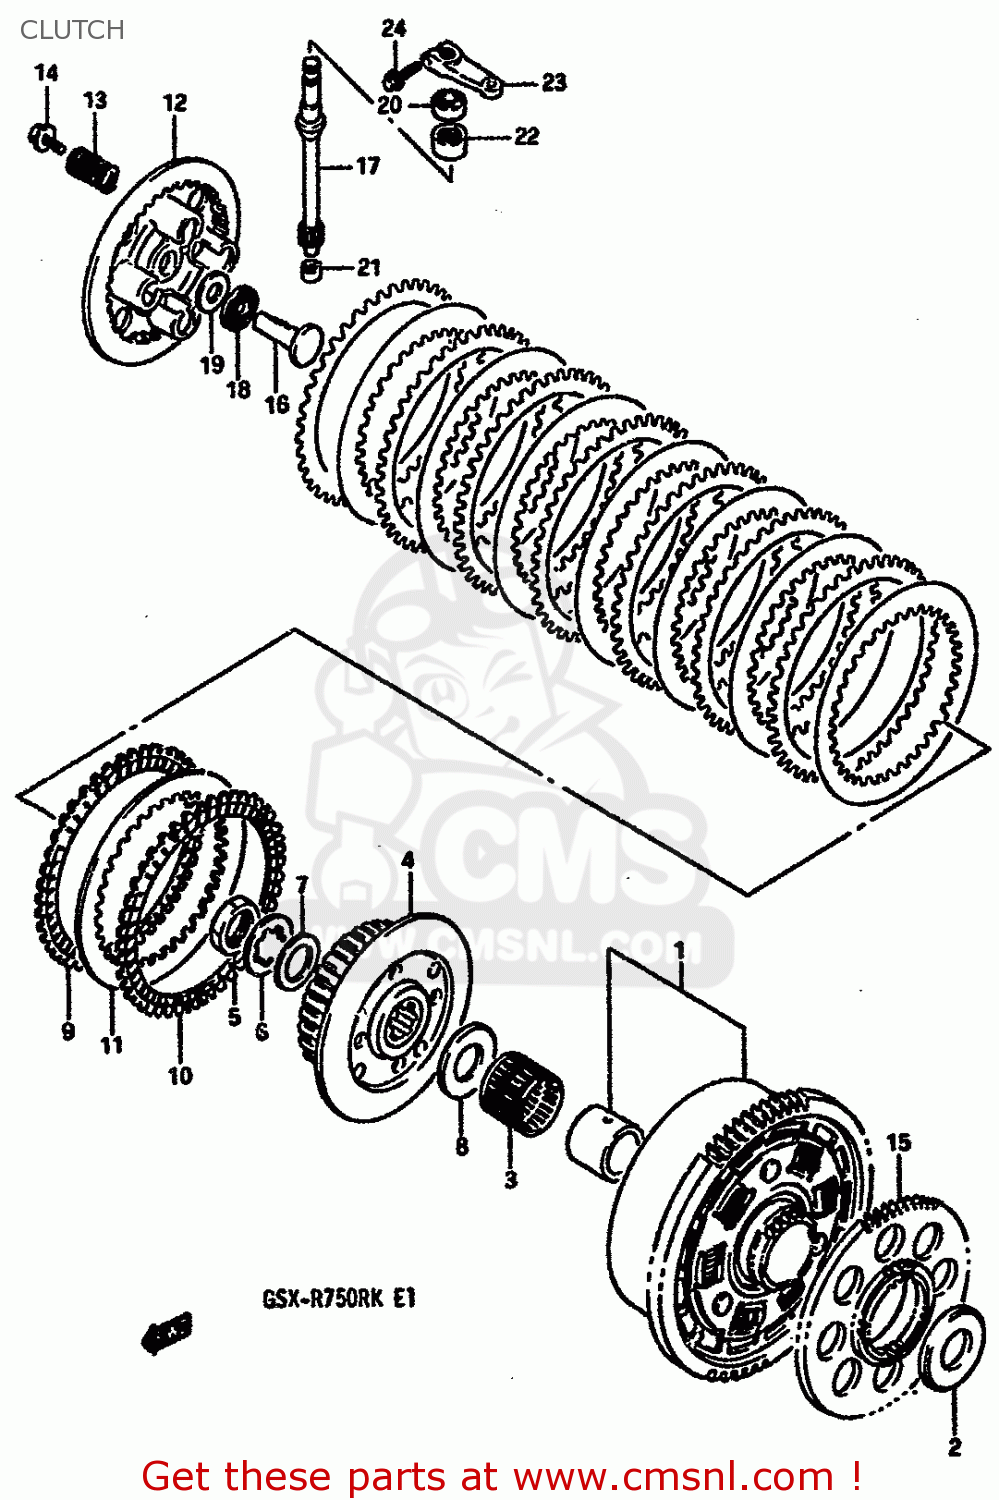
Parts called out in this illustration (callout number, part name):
1	GEAR ASSEMBLY,PRIMARY DRIVE
2	WASHER(25X54X2.5)
3	BEARING(35X40X35.8)
4	HUB,CLUTCH SLEEVE
5	NUT
6	WASHER,LOCK
7	WASHER
8	WASHER(25X50X2.5)
9	PLATE,CLUTCH DRIVE (NAS)
10	PLATE,CLUTCH DRIVE NO.2 (NAS)
11	PLATE,CLUTCH DRIVEN (NAS)
12	DISC,PRESSURE
13	SPRING
14	BOLT
15	GEAR,GENERATOR DRIVE
16	RACK,CLUTCH RELEASE
17	PINION,CLUTCH RELEASE
18	BEARING(15X28X2)
19	WASHER
20	OIL SEAL
21	BEARING 10X14X10
22	BEARING(15X22X12)
23	ARM,CLUTCH RELEASE
24	BOLT
